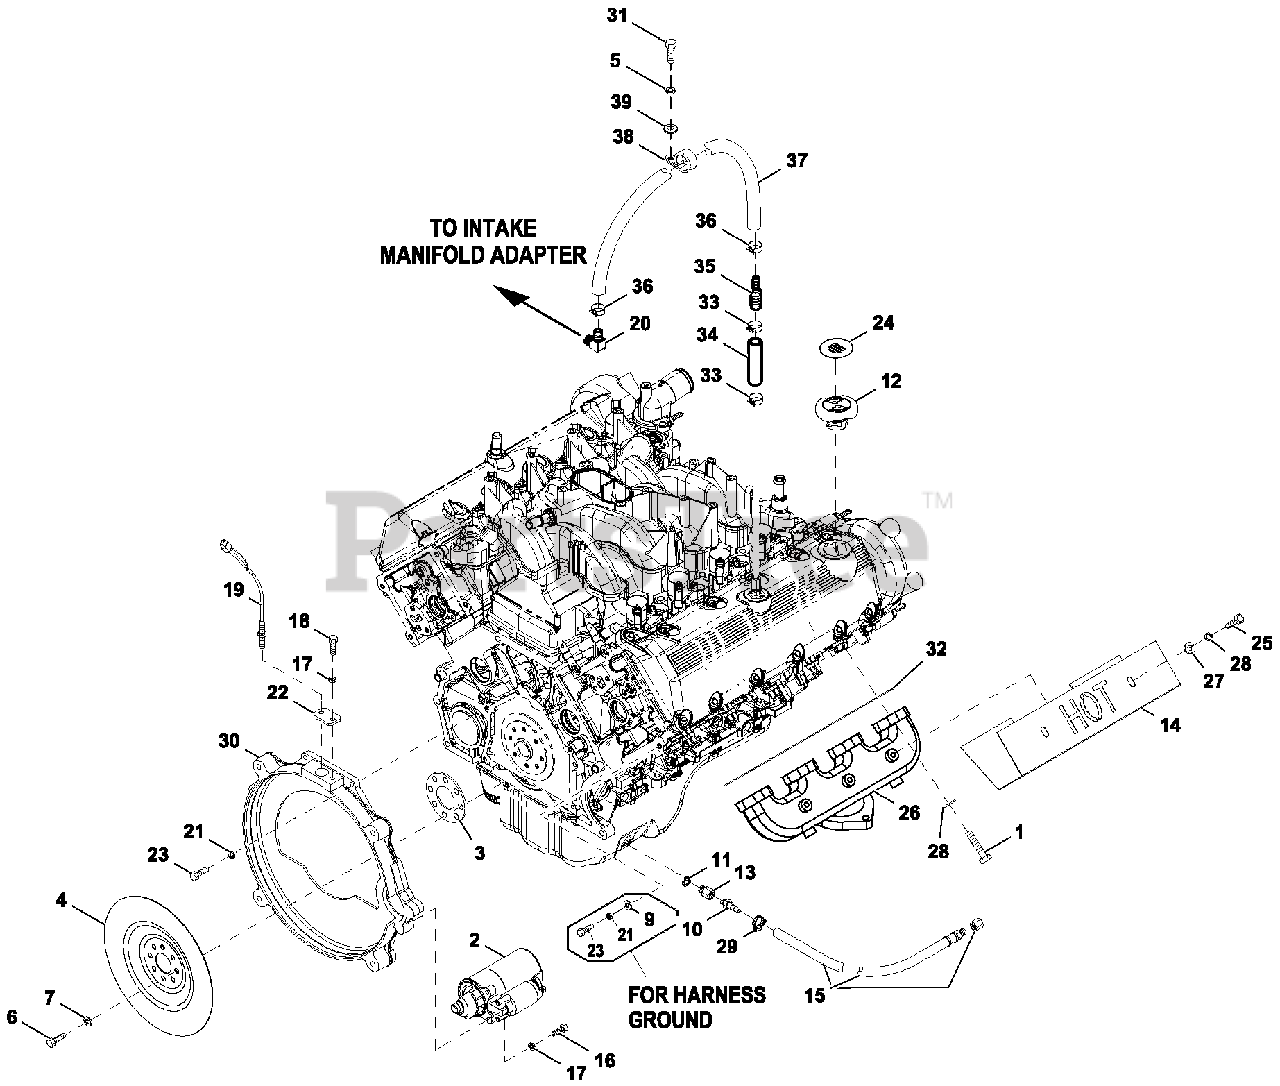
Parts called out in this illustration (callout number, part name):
1	SCREW SHC M8-1.25 X 35 SS
2	STARTER MOTOR 12V
3	SPACER FLEXPLATE 5.4L/6.8L
4	FLEX PLATE 2 POLE 5.4L/6.8L
5	WASHER LOCK M6-1/4
6	SCREW HHC M10-1.0X 25 G10.9
7	WASHER FLAT M10 HEAVY DUTY
9	WASHER FLAT 3/8-M10 ZINC
10	BARBED STR 3/8 NPT X 3/8
11	WASHER NYLON .565
12	CAP, OIL FILLER
13	ADAPTER M14-1.50X3/8NPTA
14	HEAT SHLD EXHAUST MANIFOLD
15	HOSE DRAIN ASSY 28"
16	SCREW SHC M8-1.25 X 30 G12.9
17	WASHER LOCK M8-5/16
18	SCREW HHC M8-1.25X20 G8.8
19	ASSY MAGPIC KUP&3/8-24 MALE)
20	BARBED EL 90 1/4NPTX 3/8
21	WASHER LOCK M10
22	PLATE MAG PIC K-UP ADAPTOR
23	SCREW SHC M10-1.5X55G12.9
24	DECAL REFER TO OWNERS MANUAL
25	SCREW HHC 5/16-18 X 1/2 SSTL
26	MACHINED MANIFOLD EXHAUST 5.4L
27	WASHER FLAT M8 SS
28	WASHER LOC K M8 SSTL
29	CLAMP HOSE .38- 87
30	ENGINE ADAPTER 5.4L/6.8L
31	SCREW HHC M6-1.0 X 16 C8.8
32	GASKET, EXHAUST MANIFOLD
33	CLAMP HOSE BAND .88"
34	HOSE COOL 5/8"ID 250+WP (2" LG)
35	HOSE BARB REDUCER 5/8"-3/8"ID
36	CLAMP HOSE BAND .63
37	HOSE 3/8 ID SINGLE BRAID (15" LG)
38	CLAMPSTL/VNL .75X.343Z
39	WASHER FLAT 1/4-M6 ZINC
